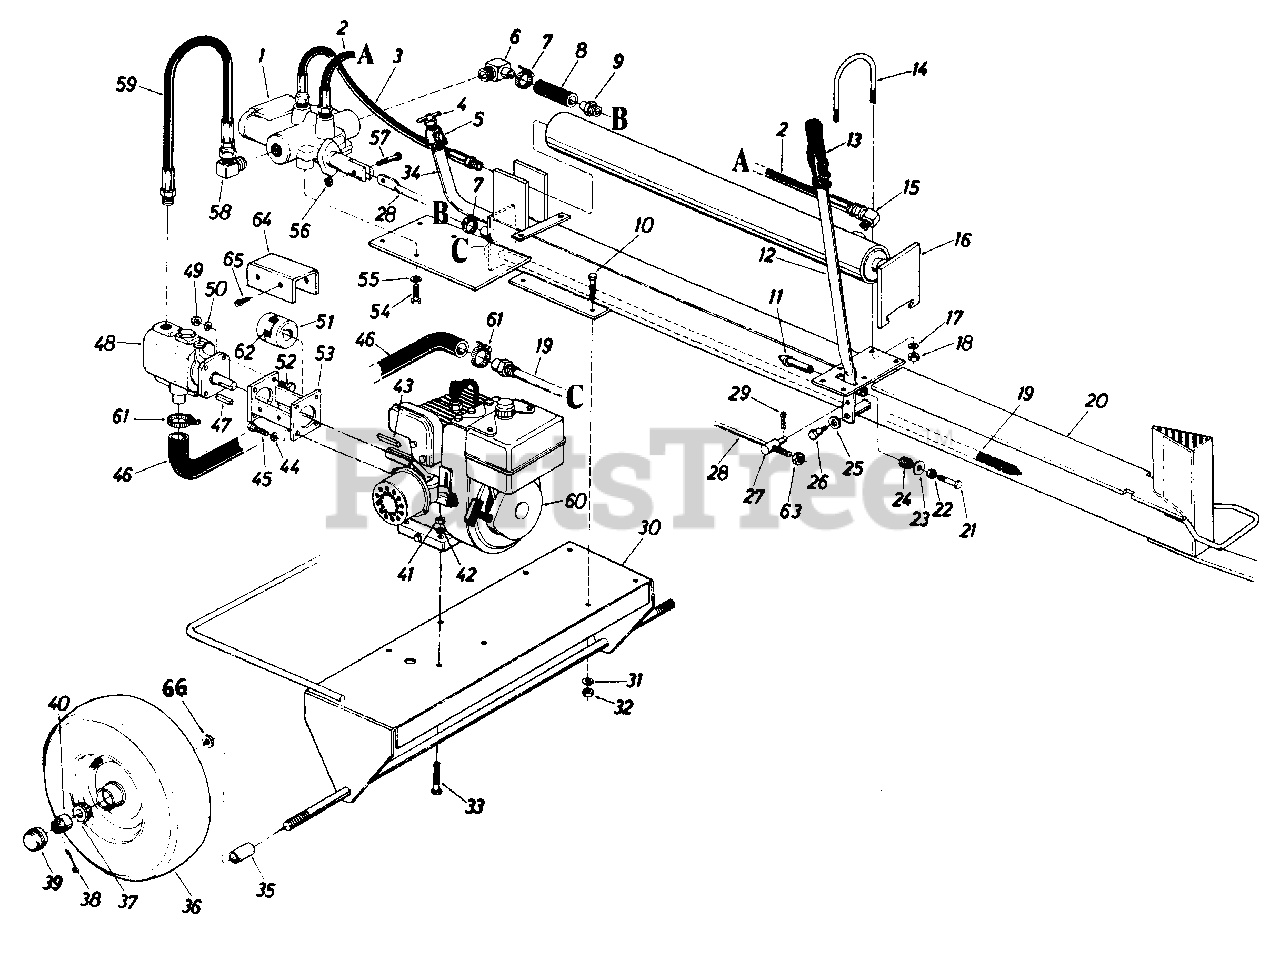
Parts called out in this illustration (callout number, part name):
1	Control Valve
2	Return Stroke High Pressure Hose
3	Forward Stroke High Pressure Hose
4	Breather Valve
5	Female Adapter 3/4-14 x 1/4-18 N.P.T.F.
6	Return Elbow
7	Hose Clamp 3/4" I.D.
8	Return Hose 3/4" I.D. x 2.62" Lg.
9	Nipple 1/2-14 N.P.T.F. x 1.5" Lg.
10	Hex Bolt 5/16-24 x 1.00" Lg. (Grade 5)
11	Return Stroke Stop Plunger
12	Engagement Handle
13	Grip
14	Cylinder Support Rod (for 3-1/2" Dia.)
15	High Pressure 90° Elbow 3/8 N.P.T. x 9/16-18
16	Cylinder Ass'y.
17	L.-Wash. 3/8" I.D.
18	Hex Nut 3/8-16 Thd.
19	Strainer Tube Ass'y.
20	Complete Oil Tank & Beam
21	Hex Bolt 5/16-24 x 1.50" Lg.
22	Hex Nut 5/16-24 Thd.
23	Fl.-Wash. .34 I.D. x .88" O.D.
24	Compression Spring .64 O.D. x .81 Lg.
25	Fl.-Wash. .53" I.D. x .94" O.D.
26	Shld. Bolt .500" Dia. x .340
27	Pivot Bushing
28	Engagement Rod .38 Dia. x 31" Lg.
29	Cotter Pin 3/32" Dia. x .75" Lg.
30	Frame Ass'y.
31	L-Wash. 5/16" I.D.
32	Hex Nut 5/16-24 Thd.
33	Hex Bolt 5/16-24 x 1.75" Lg.
34	Filler Tube
35	Spacer.75" I.D. x 1.12" O.D. x 1.56" Lg.
37	Tapered Roller Bearing
38	Cotter Pin 5/32" Dia. x 1.00" Lg.
39	Hub Cap
40	Hex Castle Nut 3/4-16 Thd.
41	Hex Nut 5/16-24 Thd.
42	L.-Wash. 5/16" I.D.
43	Sq. Key 1/4" x 1/4" x 1.00" Lg.
44	L.-Wash. 5/16" I.D.
45	Hex Bolt 5/16-24 x .75" Lg.
46	Suction Hose
47	Sq. Key
48	Pump with Sq. Key 1/8" x 1/8" x 1.00" Lg.
49	Hex Nut 5/16-24 Thd.
50	L.-Wash. 5/16" I.D.
51	Flexible Coupling
52	Hex Bolt 5/16-24 x 1.00" Lg.
53	Coupling Support Brkt. Ass'y.
54	Hex Bolt 3/8-16 x .75" Lg.
55	Belleville Wash. 3/8" I.D.
56	Hex Cent. L.-Nut 1/4-20 Thd.
57	Hex Bolt 1/4-20 x 1.25" Lg.
58	90° Solid Male Adapter
59	High Pressure Hose Ass'y.
60	Engine
61	Hose Clamp 1" I.D.
63	Hex Nut 3/8-24 Thd.
64	Coupling Shield
65	Hex Self Tap. Scr. 1/4-20 x .38"
66	Seal
